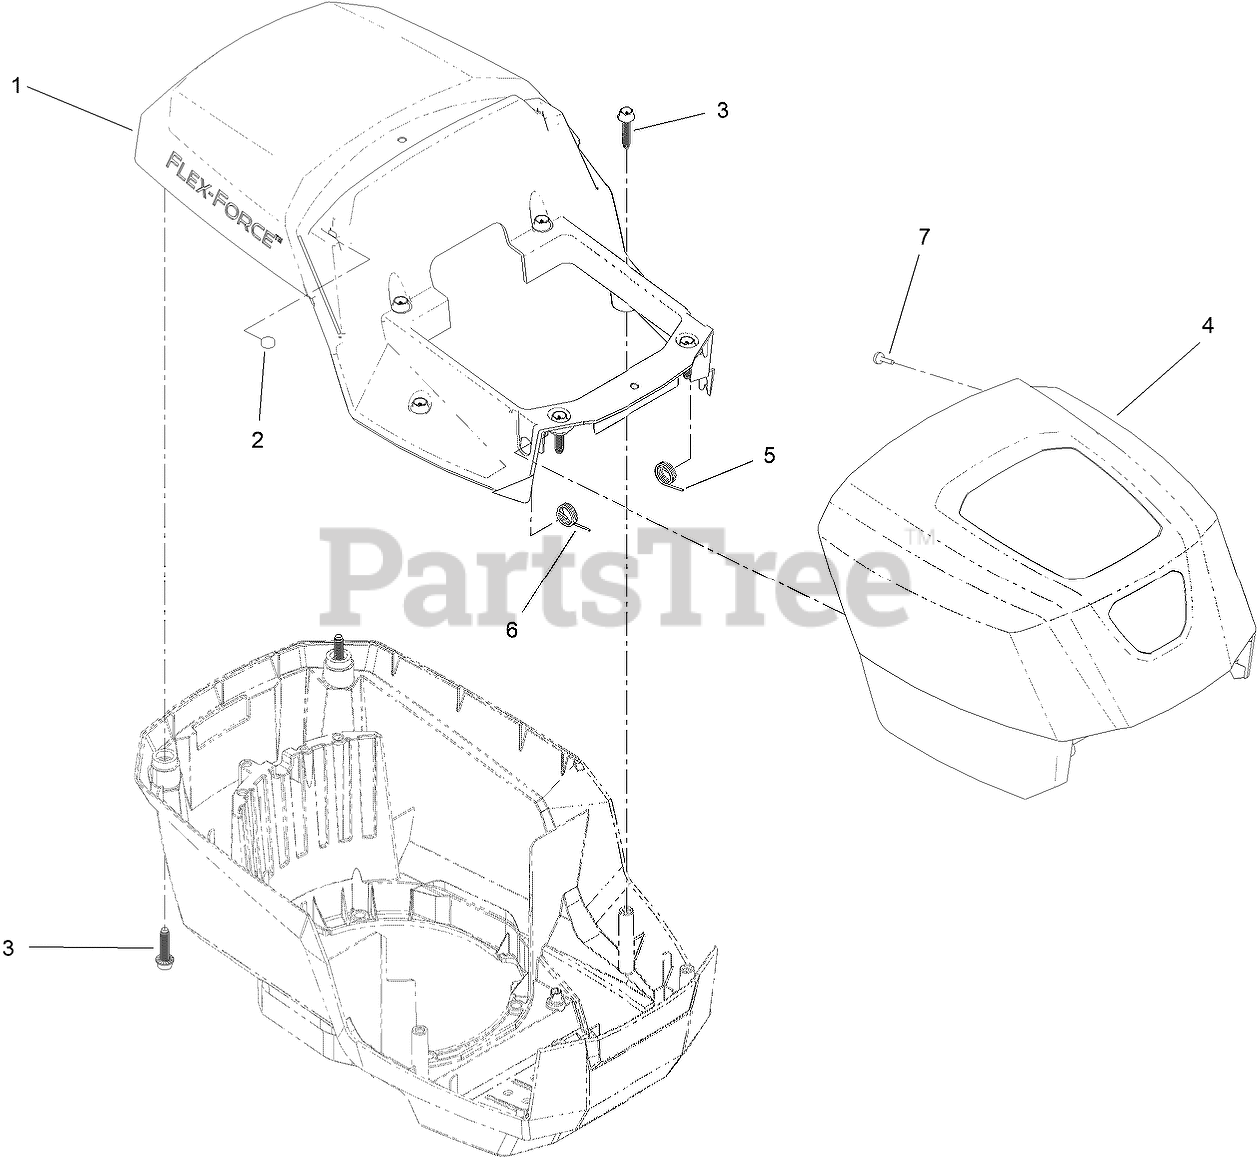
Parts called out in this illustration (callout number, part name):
1	SHROUD-UPPER
2	MAGNET
3	SCREW-FLANGE, PLASTIC
5	SPRING-LH
6	SPRING-RH
7	SCREW-PPH
